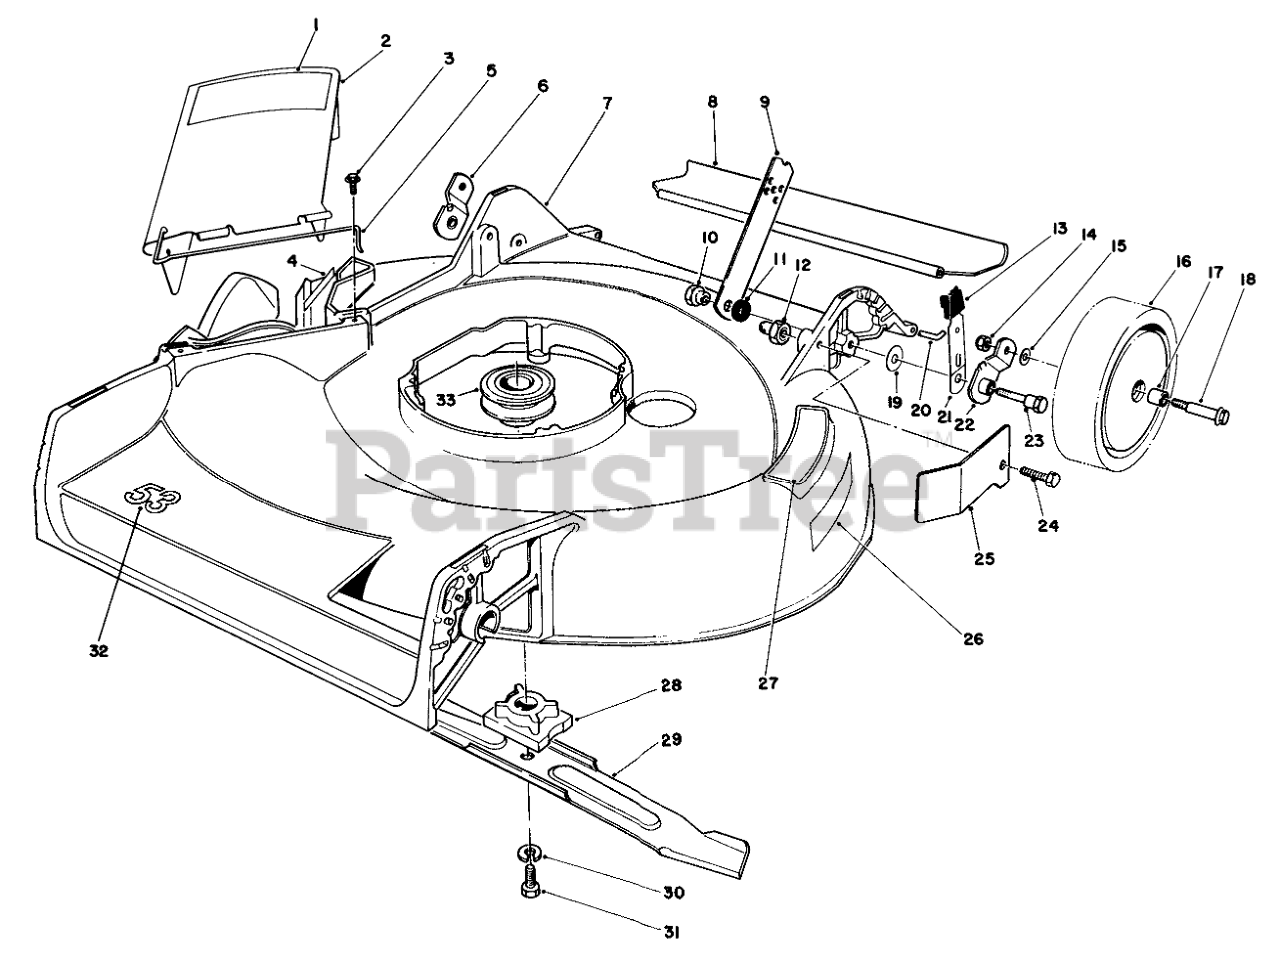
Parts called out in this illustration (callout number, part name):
1	DECAL - DANGER DEFL
2	Deflector Cover Assembly (Incl. Ref. #1)
3	SCREW-HWH
4	DANGER DECAL
5	SPRING HINGE
6	Pivot Arm
7	Housing (Incl. Ref. #26)
8	REAR SAFETY SHIELD 21
9	HANDLE LATCH
10	HANDLE PIVOT NUT
11	SPACER
12	HANDLE PIVOT NUT
13	KNOB-ARM
14	Nut
15	WASHER
16	Wheel & Tire Assembly (Incl. Ref. #17)
17	BUSHING
18	BOLT-WHEEL
19	WASHER-PIVOT
20	SHIELD ROD
21	SPRING ARM ASM
22	Pivot Arm
23	PIVOT SCREW
24	SCREW-HH
25	MUFFLER SHIELD
26	Decal Danger
27	DECAL - STEP PAD INT'L
28	BLADE RETAINER
29	Blade
30	WASHER-LOCK
31	SCREW-HH
32	DECAL - 53
33	Pulley
